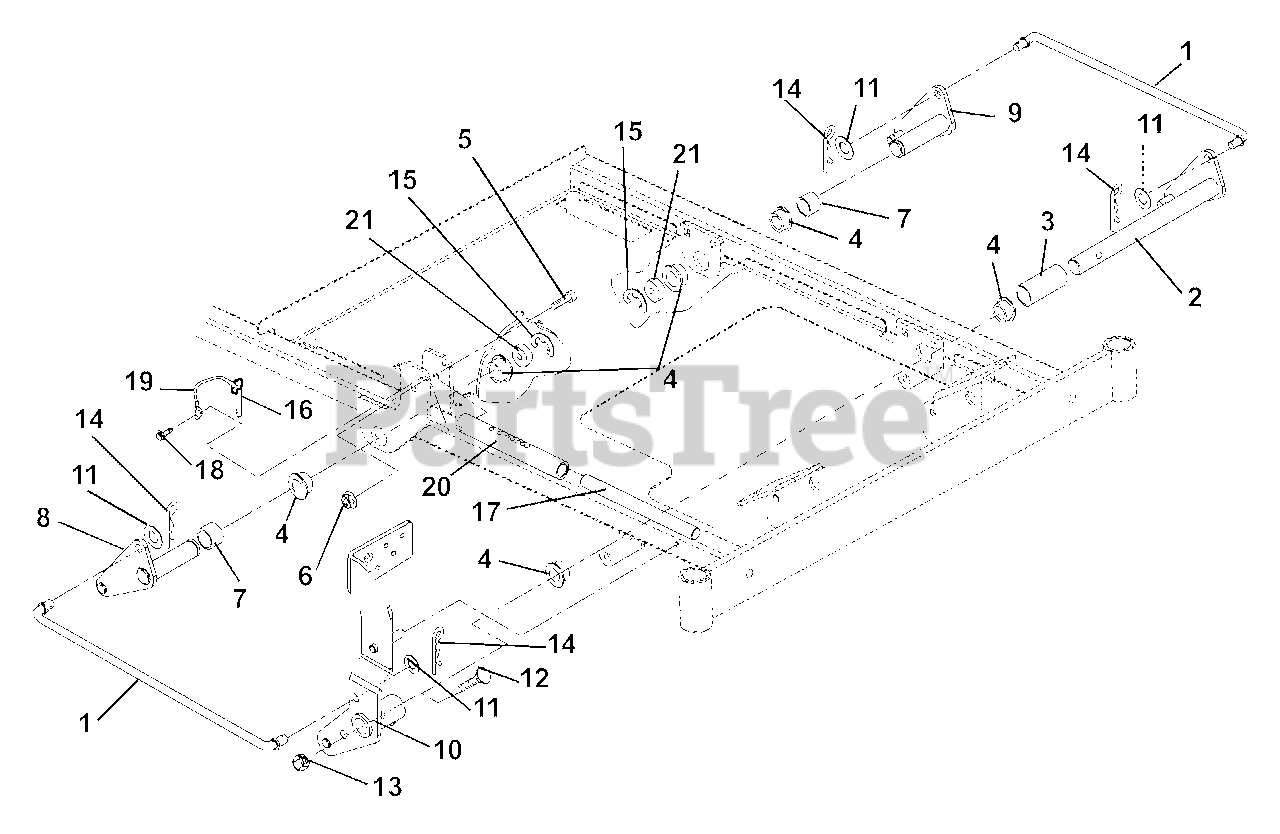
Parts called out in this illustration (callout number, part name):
1	ROD, LIFT
2	WELDMENT,FRONT LIFT
3	BSHG, SPCR 1.01X1.25X2.63 PM
4	BSHG-FLG 1.000X1.12X.62X1.50BR
5	@BLT-HEX .38-16X2.75 GR5 YWZC
6	@NUT-LK-NYL-FLG .38-16 YWZC
7	BSHG-SPCR 1.032X1.250X.88 PM
8	WELDMENT, LIFT, REAR - RH
9	WELDMENT, LIFT, REAR - LH
10	WMT, FOOT PEDAL
11	@WSHR-FL-STL.531X1.06X.095YWZC
12	@BLT-HEX .38-16X2.00 GR5 YWZC
13	@NUT-LK-NYL-FLG .38-16 YWZC
14	PIN, HAIR, EXT - #16 YWZC
15	RG-RTNG .822X1.500X.050 TYP E
16	PIN, SPRING BALL .375OD X 1.50
17	ROD, LIFT
18	@SCR-TAP .25-20X.37 HWH YWZ TR
19	CBL,HOOD
20	TUBE, LIFT STOP
21	BSHG, SPCR 1.032X1.25X.25 PM
